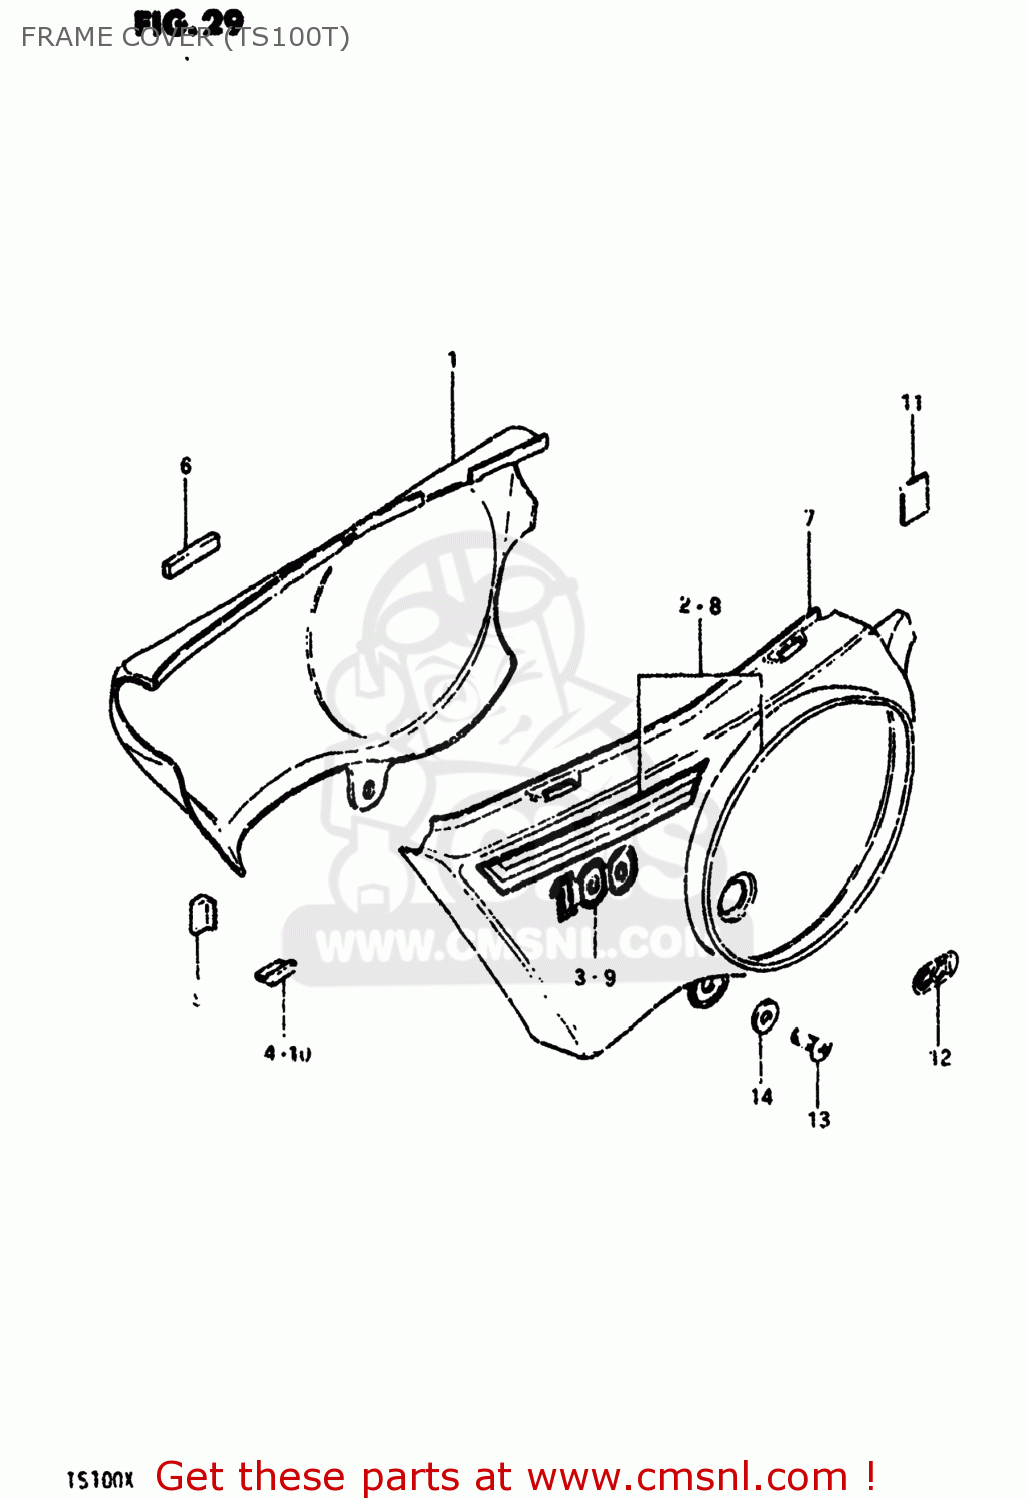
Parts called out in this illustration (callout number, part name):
1	COVER,FRAME,RIGHT
2	TAPE SET,FRAME COVER
3	EMBLEM
4	CUSHION,FRAME COVER
5	CUSHION,FRAME COVER
6	CUSHION,FRAME COVER
7	COVER,FRAME,LEFT
8	TAPE SET,FRAME COVER
9	EMBLEM
10	CUSHION,FRAME COVER
11	PROTECTOR(170X95X3.0)
12	EMBLEM,CCIS
13	SCREW 6X12
14	WASHER
